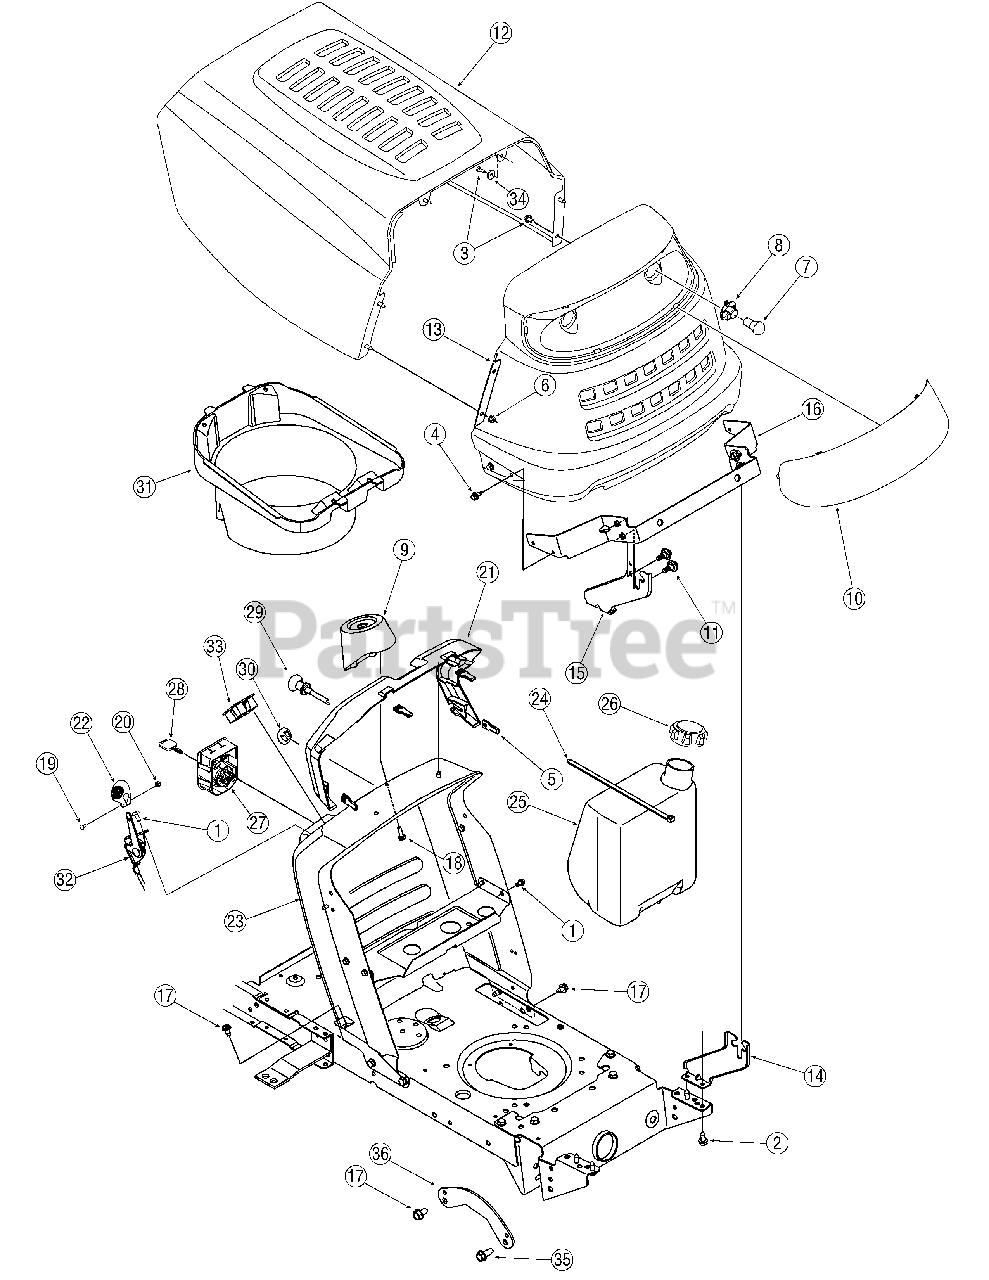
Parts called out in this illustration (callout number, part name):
1	Screw, 1/4-20, 0.500
2	Screw, 5/16-12, 0.750
3	Screw, 1/4-20, .620, Gr5
4	Screw, 1/4-20, .625
5	Nut, 1/4-20, Speed U-type
6	Nut, Flange Lock, 1/4-20, GrF, Nylon
7	Headlamp, 12V
8	Headlamp Socket
9	Support, Steering
10	Lens
11	Screw, Shoulder, .43 x.29, 5/16-18
18	Screw, 1/4-15, 0.750
19	Screw, Machine, #8-32, 0.375
20	Nut, Hex, #8-32, GrA
21	Collar, Dash
22	Knob, Control
24	Cable Tie, 34.75
25	Fuel Tank, 1.5 gal.
26	Fuel Tank Cap
27	Module, Ignition Switch
28	Key
29	Choke Control, 37.5"
31	Plenum (Single Cylinder Engine)
31	Plenum (Twin Cylinder Engine)
32	Throttle/Choke Control, 25" (Single Cylinder Engine)
32	Throttle Control, 39" (Twin Cylinder Engine)
33	Ammeter
34	Flat Washer .265 x .938 x .120
35	Screw, 5/16-18, 0.750
